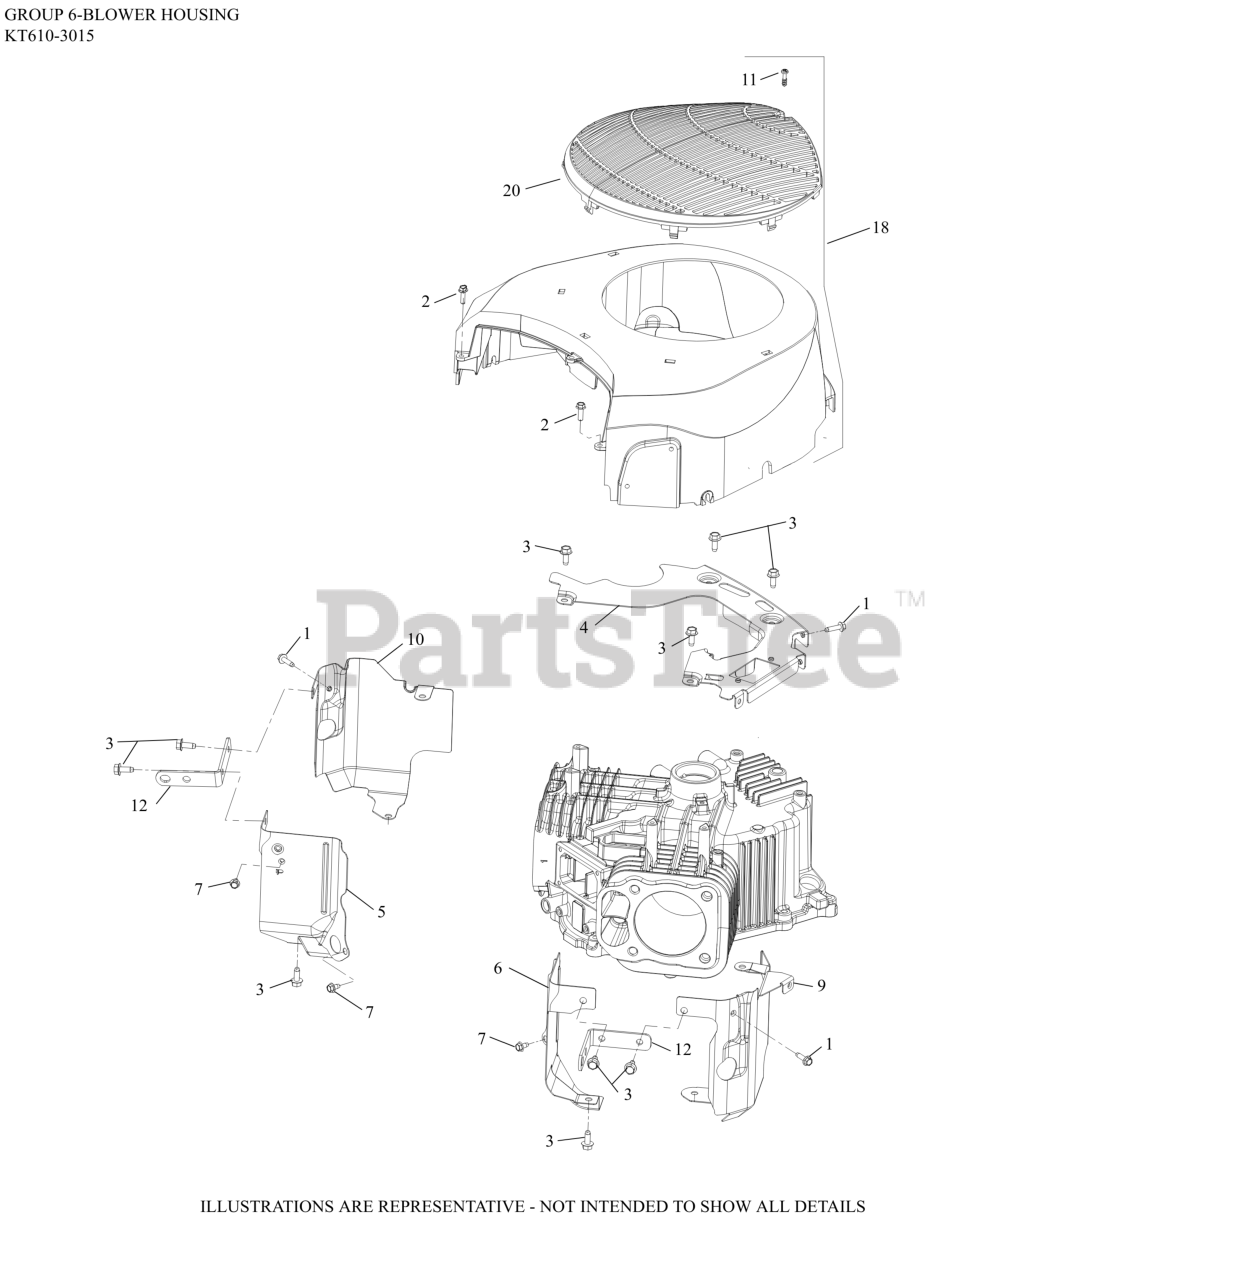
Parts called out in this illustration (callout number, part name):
1	SCREW, THD FRM-USE 25 086 473-S
2	SCREW, HI-LOW
3	SCREW, THREAD FORMING
4	PLATE, BACKING
5	BAFFLE, VALLEY #1
6	BAFFLE, VALLEY #2
7	SCREW, THREAD FORMING
9	BAFFLE, LEFT BARREL
10	BAFFLE, RIGHT BARREL
11	SCREW, M5-2.42 (PT) THREAD
12	STRAP, LIFTING
18	KIT, BLOWER HOUSING
19	CLIP, BLOWER HOUSING
20	GUARD, FIXED
22	BOLT, ENGINE GROUND
